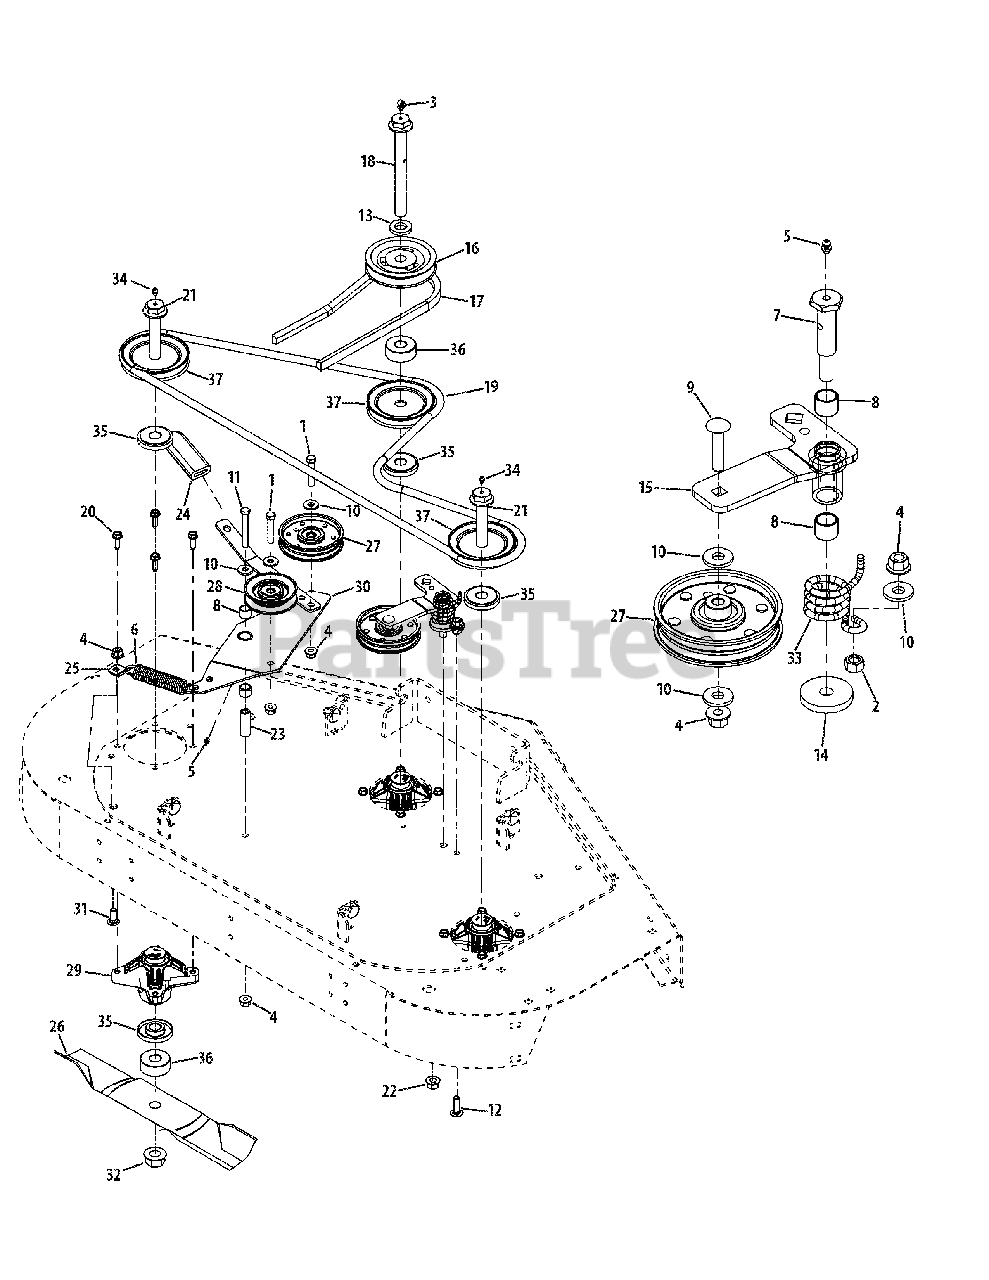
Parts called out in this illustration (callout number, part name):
1	Hex Screw, 3/8-16 x 2.00
2	Nut, 3/8-16
3	Grease Fitting, 1/4-28 x .788
4	Flange Counterlock Nut, 3/8-16
5	Grease Fitting, 1/4-28
6	Extension Spring, 1.00 x 5.00 x .125
7	Shoulder Bolt, .625 x 1.95
8	Sleeve Bearing, .628 x .753 x .625
9	Carriage Bolt, 3/8-18 x 1.75
10	Washer, .406 x 1.00 x .105
11	Hex Screw, 3/8-16 x 2.75
12	Carriage Bolt, 3/8-16 x 1.25
13	Spacer, .812 x 1.47 x .218
14	Washer, .438 x 1.75 x .250
15	Idler Arm Assembly
16	Pulley (48 Inch Deck)
16	Pulley (54 Inch Deck)
17	V-Belt (48 Inch Deck)
17	V-Belt (54 Inch Deck)
18	Hex Screw, 3/4-16 x 7.16
19	V-Belt (48 Inch Deck)
19	V-Belt (54 Inch Deck)
20	Hex Flange Screw, 5/16-18 x 1.00
21	Hex Flange Screw, 3/4-16 x 5.4
22	Flange Counterlock Nut, 7/16-14
23	Spacer, .390 x .625 x 1.88
24	Flat Grip, 1.0 x 3.2 x .25
25	Spring Mount Bracket
26	Hi-Lift Blade, 17.0
26	Hi-Lift Blade, 19.0
27	Idler Pulley
28	Idler Pulley
29	Spindle Assembly
30	Double Idler
31	Carriage Bolt, 3/8-16 x 1.00
32	Flange Lock Nut, 3/4-16
33	Torsion Spring (48" Deck)
33	Torsion Spring (54" Deck)
34	Drive Lube Fitting
35	Deck Spindle Spacer
36	Spacer, .760 x 2.000 x .790
